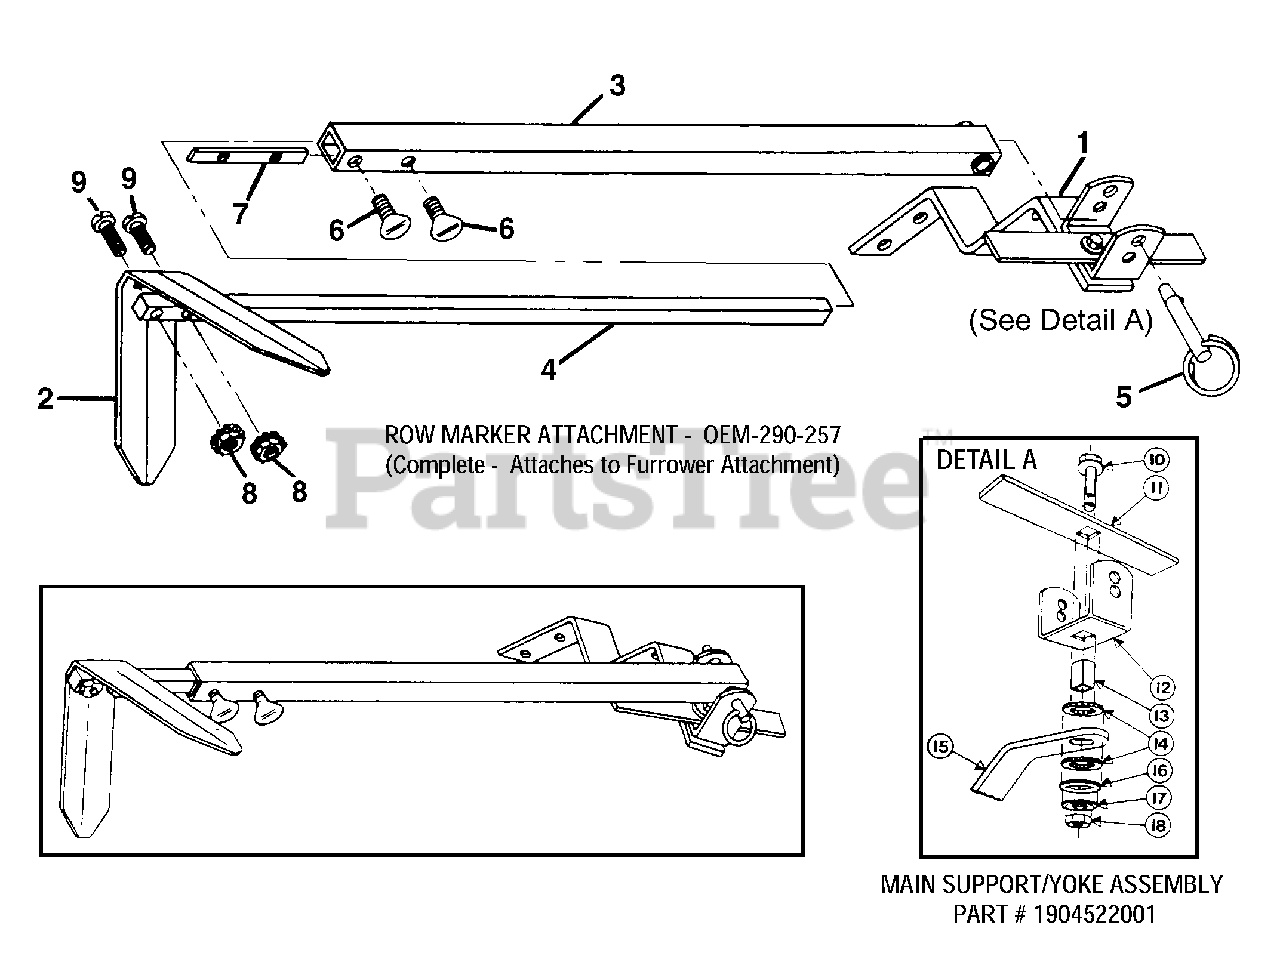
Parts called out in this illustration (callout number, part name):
1	Main Support & Yoke Assy-complete.
2	Marker Blade-blade only
3	Marker Arm-main arm
4	Marker Arm-extension arm with stop pin
5	Hitch Pin-
6	Thumbscrew-1/4-20 x 1/2, not avail. sep.
7	Nut Bar-
8	Nut-hex, 10-24 w/attached start washers, not avail. sep.
9	Screw-round hd.,10-24 x 1, not avail. sep.
10	Screw-hex flanged locking, 3/8-16 x 1-1/2
11	Stop Bar
13	Tube Key-square
14	Washer-friction
15	Main Support
16	Washer-square hole
17	Washer-disc spring
18	Nut-hex 3/8-16
